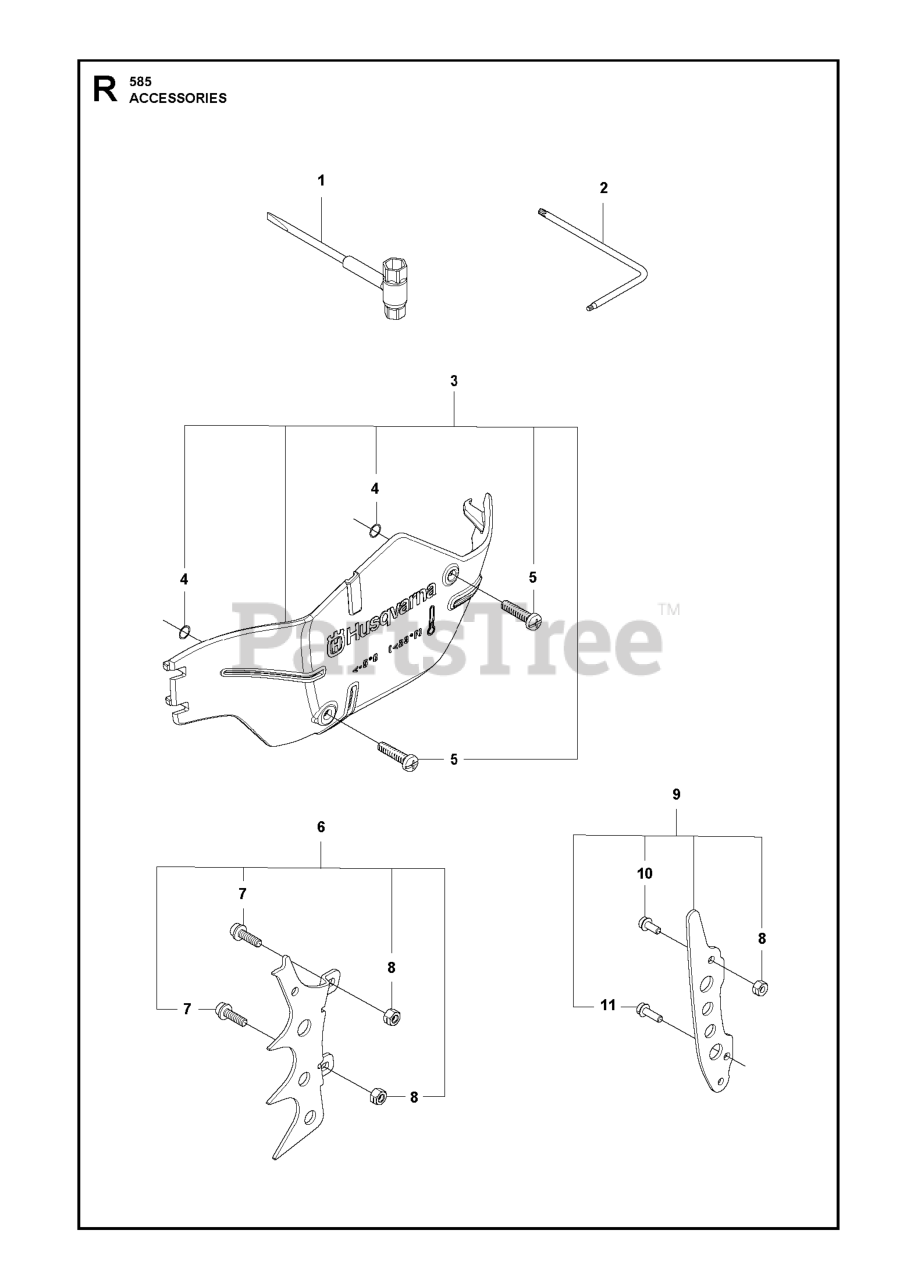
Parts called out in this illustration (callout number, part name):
1	COMBINATION WRENCH 13/16
3	WINTER KIT 585/592
6	SPIKE KIT OUTER NON-WRAP H592
9	BUMPER KIT H585/592XP/XPG
10	SCREW
